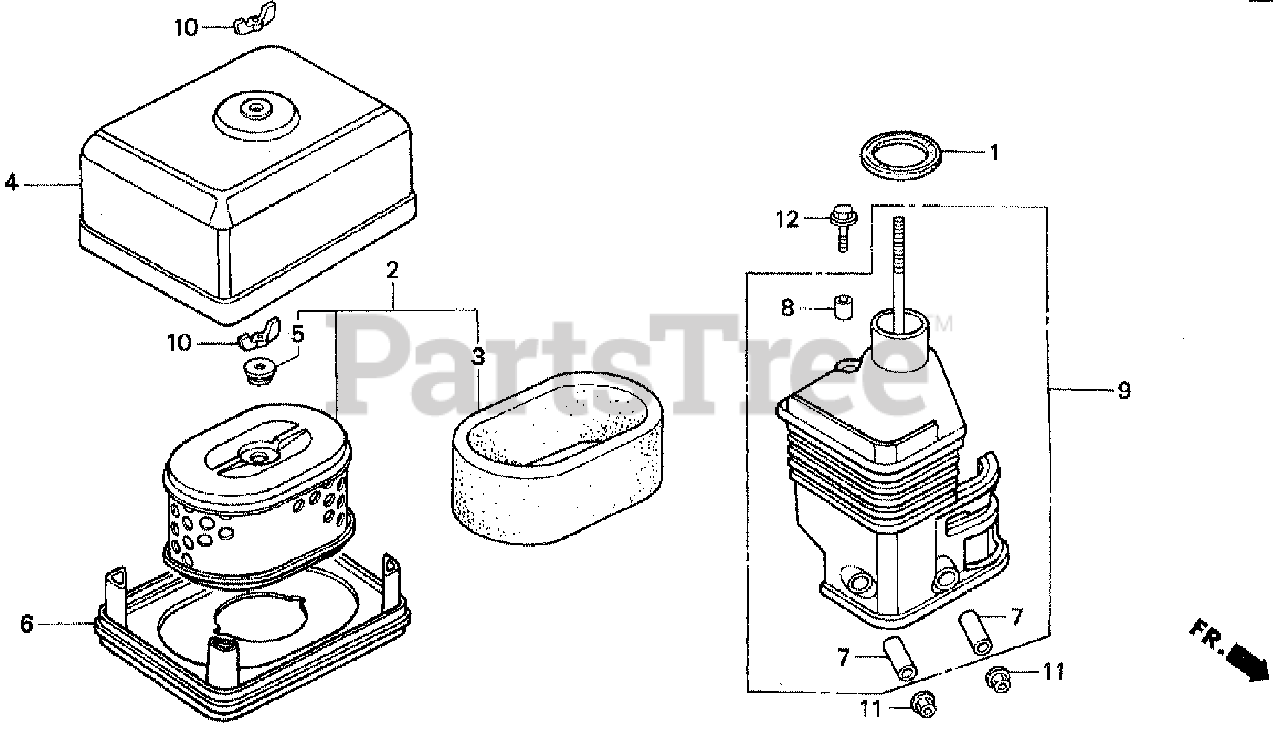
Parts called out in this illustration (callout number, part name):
1	GASKET, ELBOW
2	ELEMENT, AIR CLEANER (DUAL)
3	FILTER (OUTER)
4	COVER, AIR CLEANER (DUAL)
5	GROMMET, AIR CLEANER
7	COLLAR, AIR CLEANER
8	COLLAR B, AIR CLEANER
9	ELBOW, AIR CLEANER
10	WINGNUT, TOOL BOX SETTING
11	NUT, FLANGE (6MM)
12	BOLT, FLANGE (6X20)
